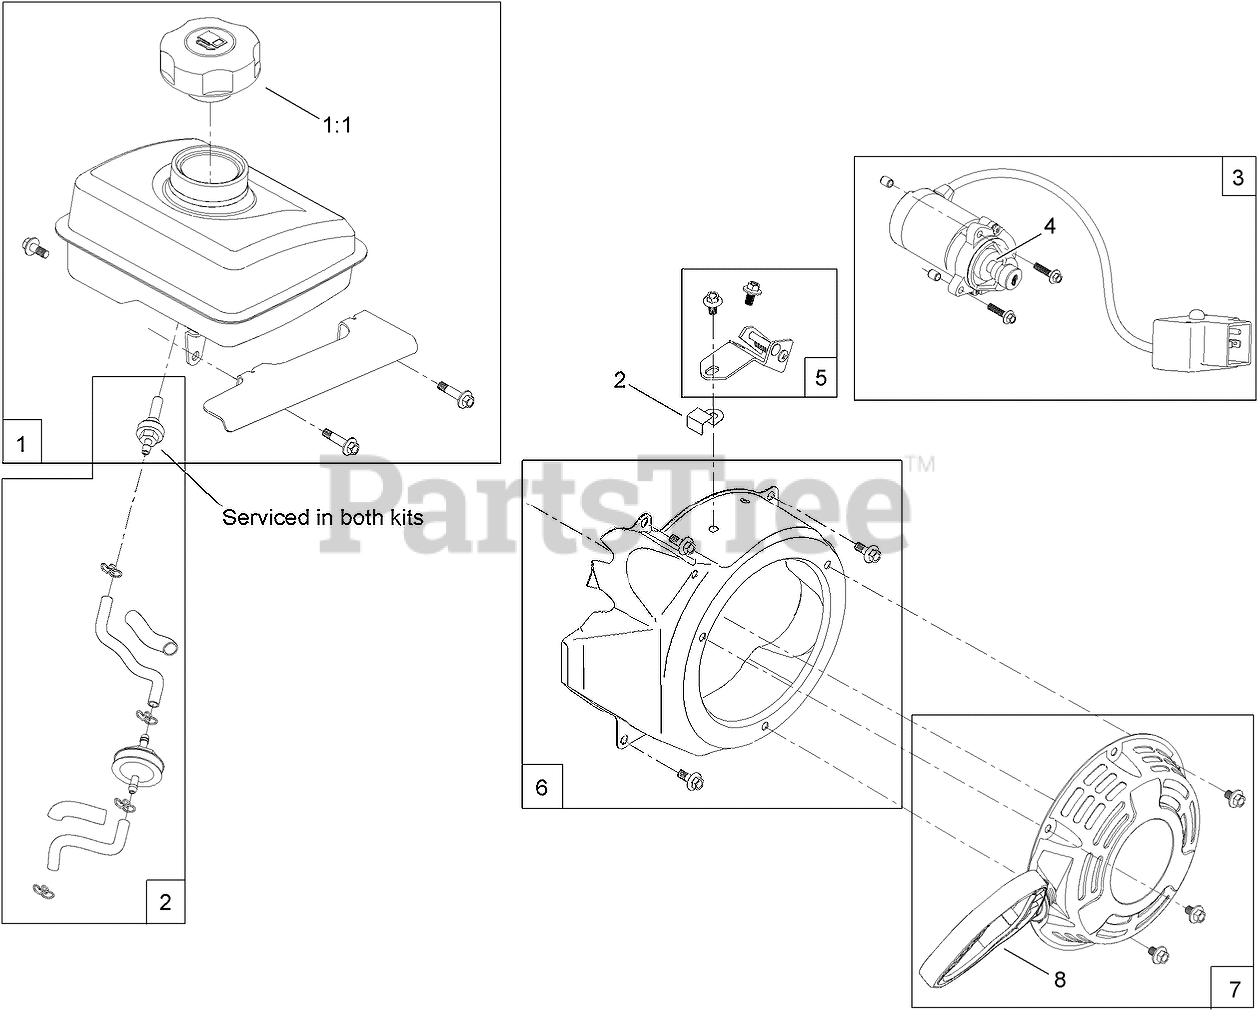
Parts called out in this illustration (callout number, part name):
1	FUEL TANK AND CAP KIT
1:1	CAP-FUEL
2	FUEL LINE KIT
3	ELECTRIC STARTER KIT
4	PINION KIT
5	GOVERNOR KIT
6	BLOWER SHROUD KIT
7	RECOIL ASM KIT
8	MITTEN GRIP KIT
